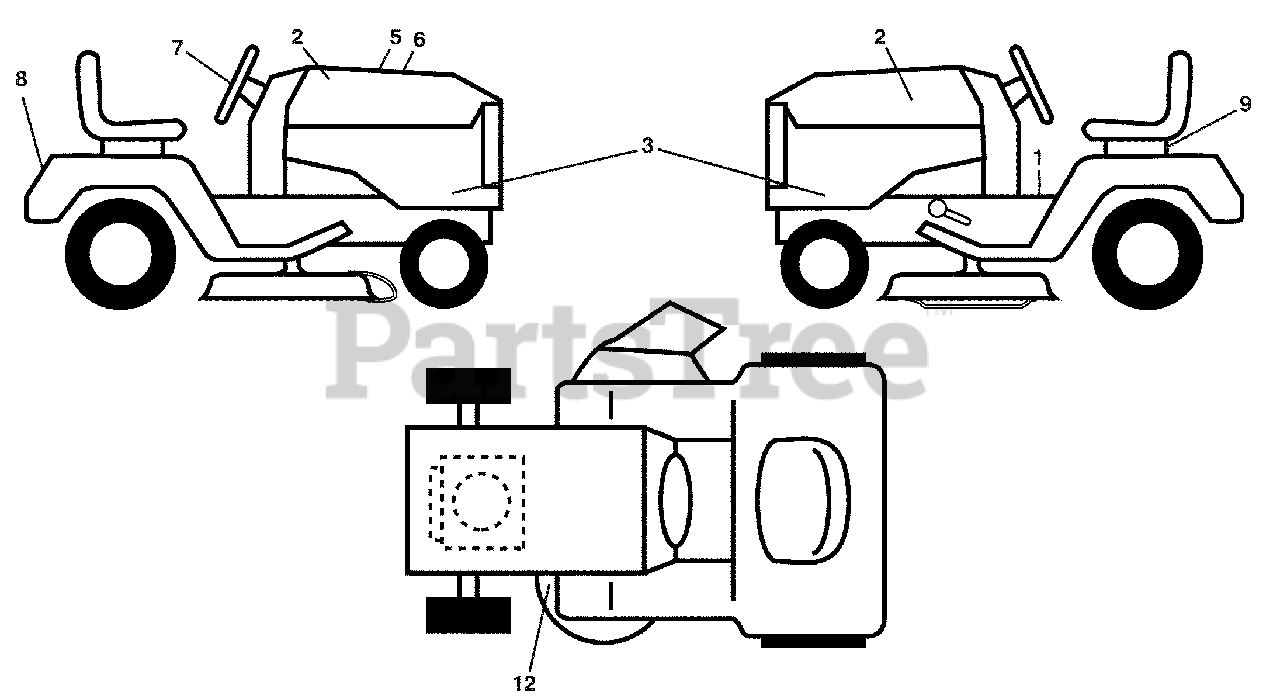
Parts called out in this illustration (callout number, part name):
1	Decal, Fender Warning
2	Decal, Hood
3	Decal, Hood Panel SD
5	Decal, Customer Respons.
6	Decal, Replacement
7	Decal, Steering Wheel
8	Decal, Fender
9	Decal, Battery Dnge/Poi
12	Decal, Mower V-Belt Schematic
